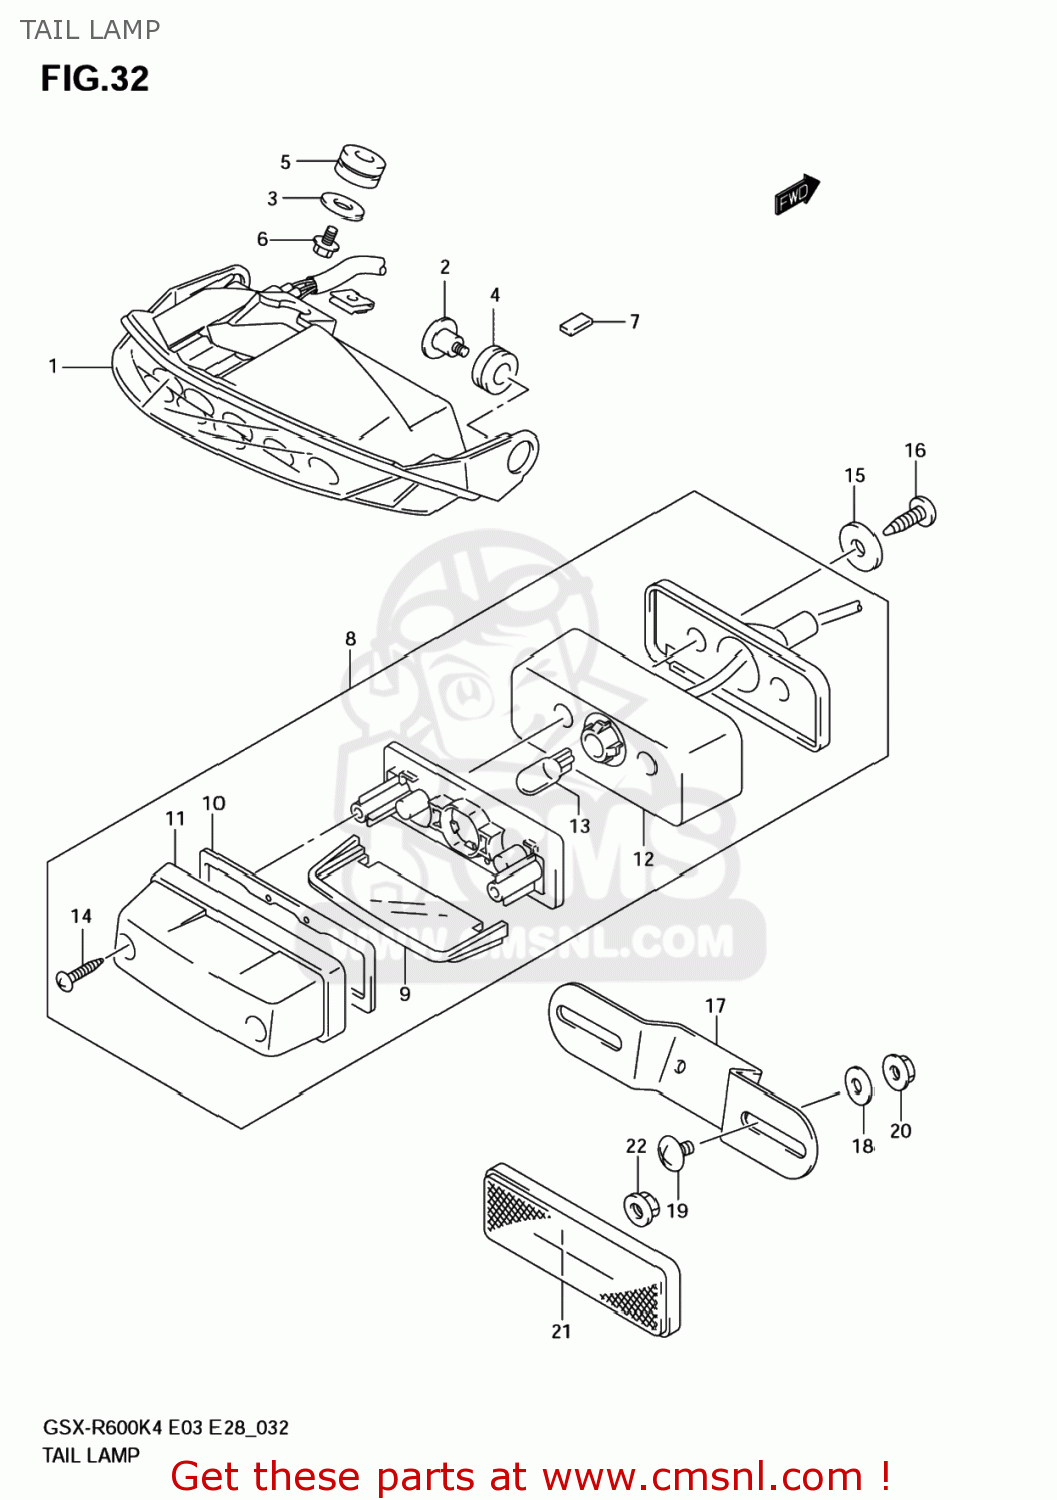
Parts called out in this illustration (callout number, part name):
1	LAMP ASSY,RR COMBINATION
2	SCREW(5X16.2)
3	WASHER(5.5X20X1.2)
4	CUSHION
5	CUSHION
6	SCREW
7	PROTECTOR(170X95X3.0)
8	LAMP ASSY,LICENSE
9	LENS
10	GASKET (NAS)
11	COVER
12	SPACER
13	BULB(12V5W)
14	SCREW
15	WASHER(5.5X20X1.2)
16	SCREW, LICENSE LAMP
17	BRACKET,LICENSE PLATE
18	WASHER(6.5X20X1.6)
19	SCREW
20	NUT
21	REFLECTOR ASSEMBLY,REAR
22	NUT
